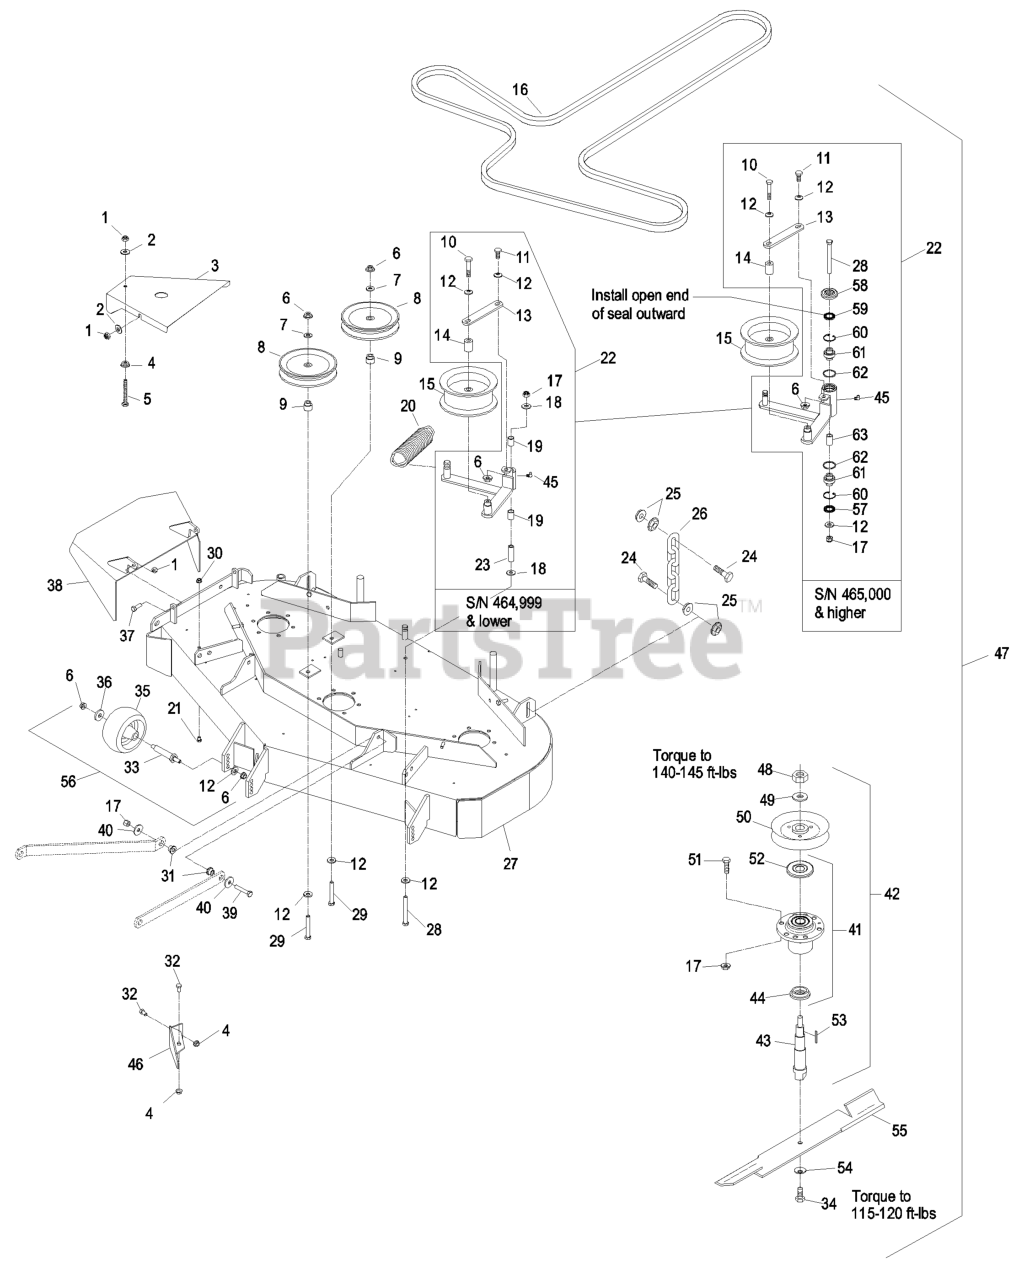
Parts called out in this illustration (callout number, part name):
1	NUT-LOCK, NI
2	WASHER-FLAT
3	SHIELD,BELT
5	BOLT,TAP HH
6	NUT-HHF, WHIZ
7	WASHER-FLAT
8	PULLEY-IDLER
9	BUSHING-IDLER
10	SCREW-HH
11	SCREW-HH
12	WASHER-BELLEVILLE
13	PLATE
16	BELT - V, B
17	NUT-LOCK, NI
18	WASHER-HARDENED
19	SLEEVE-BEARING
21	SCREW-HH
22	KIT,DECK IDLER LHP/LCT
23	BUSHING-PIVOT, IDLER
24	SCREW-CAP, HH
26	CHAIN-LIFT, DECK
27	ASM,DECK W/DECALS LCT44
28	SCREW-HH
29	SCREW-HH
31	SPACER-STRUT
32	SCREW-HH
34	SCREW-CAP
35	ROLLER-SCALP, ANTI
37	SCREW-HH
38	WLD,CHUTE 48
39	SCREW-HH
43	SPINDLE,SHAFT
44	SPACER-GUARD, BOTTOM
45	FITTING-GREASE
47	Asm, Deck Complete (44")
50	SHEAVE,W/HUB
51	SCREW-HH
52	GUARD-BEARING, TOP
53	KEY-RECTANGLE
54	WASHER-SPRING
57	SEAL-LIP, DOUBLE
58	GUARD-TOP
59	SEAL-LIP, SINGLE
60	RING-SNAP
61	BEARING-SPHERICAL
62	O-RING
63	SPACER
